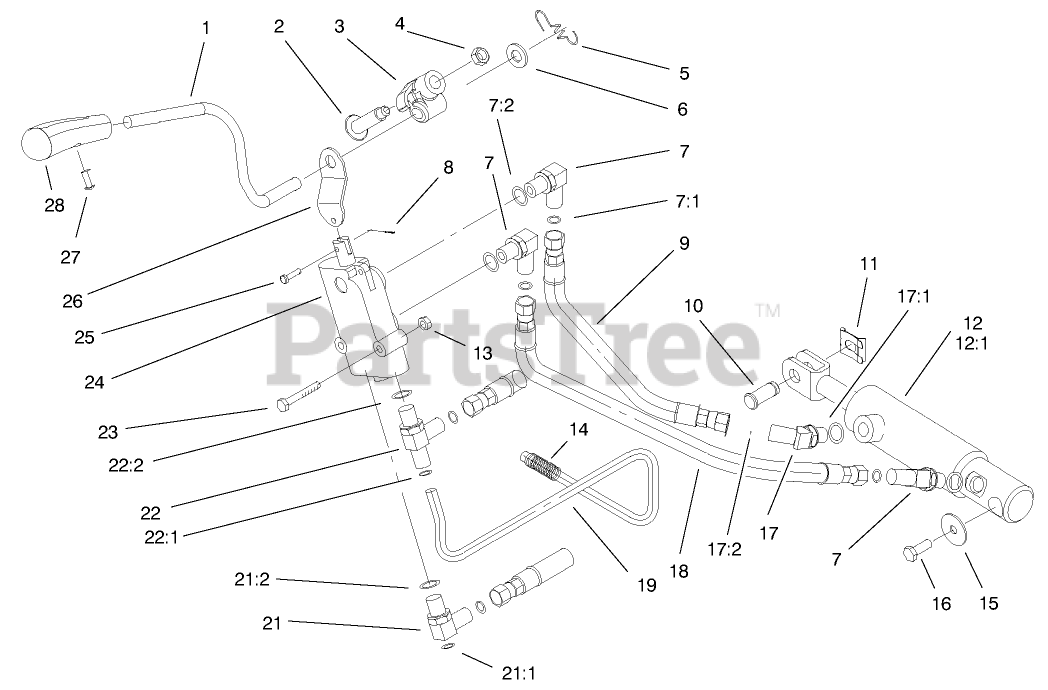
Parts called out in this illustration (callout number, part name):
1	HANDLE-LIFT
2	BOLT-SHOULDER
3	TRUNNION-LEVER, LIFT
4	NUT-JAM, LOCKING
5	SPRING-EXTENSION, LIFT
6	WASHER
7:1	O-RING
7:2	O-RING
8	PIN-COTTER
9	HOSE ASM
10	PIN-CLEVIS
11	CLIP-PIN
12	LIFT CYLINDER ASM
13	NUT-LOCK, NI
14	COVER-BRACE
15	WASHER-FLAT
16	SCREW-THREAD LOCKING
17:1	O-RING
17:2	O-RING
18	HOSE ASM
19	TUBE-HYD
21:1	O-RING
21:2	O-RING
22	FITTING-TEE
22:1	O-RING
23	SCREW-HH
24	VALVE-HYD
25	PIN-CLEVIS
26	LINK-LIFT
27	SCREW-PPHTF
28	KNOB-LIFT
